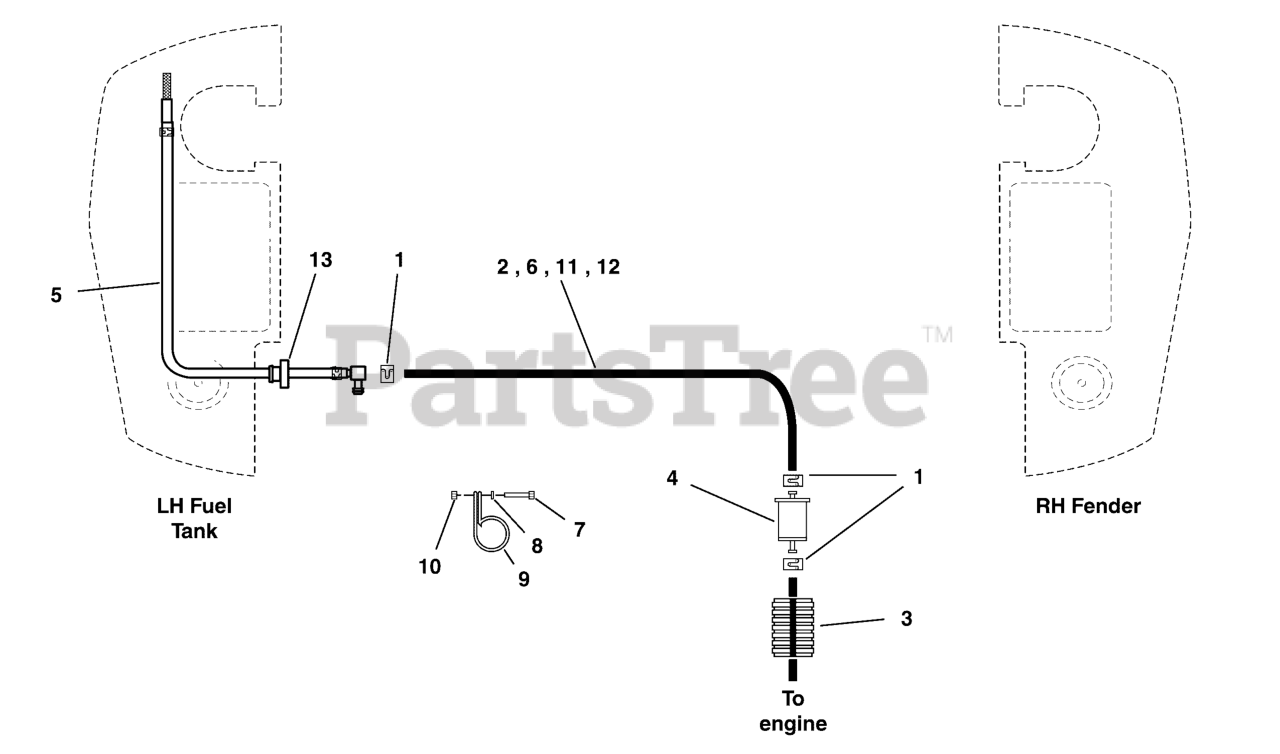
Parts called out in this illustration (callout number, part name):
1	CLAMP, Hose
2	1/4" Fuel Line, 29" Long
3	WIRE LOOM, 1/2 ID, 13.00 LONG
4	FUEL FILTER (SV)
5	PICKUP TUBE ASM, FUEL TANK, 22"
6	1/4" Fuel Line, 5" Long
7	BOLT, 1/4"-20 X 3/4" GD5 YZ
8	WASHER, 1/4 SAE
9	CLAMP, VINYL INSULATED, 1.00
10	NUT, 1/4-20 Hex Nylock Flange
11	HOSE, 1/4" FUEL, 34.00"
12	1/4" Fuel Line, 5" Long
13	BUSHING-FUEL TANK RED RUBBER
